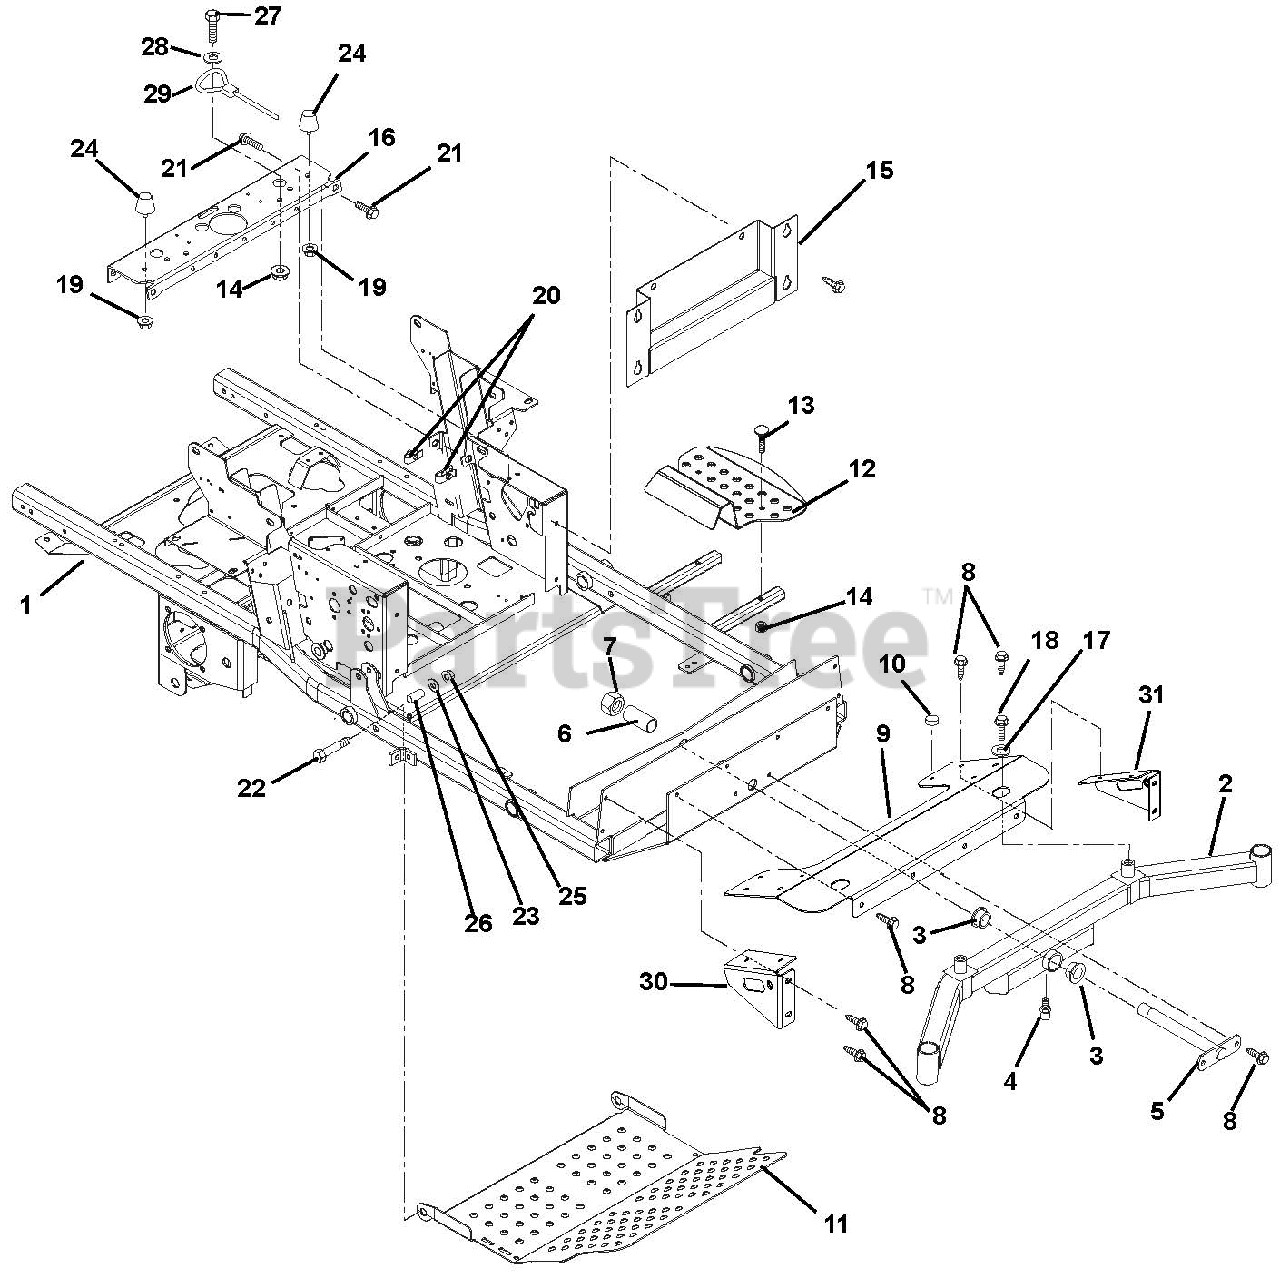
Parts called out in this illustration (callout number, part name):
1	Weldment, Frame
2	Weldment, Axle
3	Bushing, Flange 1.02 x 1.385 x .75 x 1.75
4	Fitting, Lube 45 Degree GM411031
5	Pin, Axle
7	Nut, Locking Nylon 1.00-14
8	Screw, Tapping .38-16 x .75
9	Axle Cover
10	Button, Rubber
11	Panel, Inspection
12	Step, Ingress
13	Bolt, Round Head Square Neck .31-18 x 1.75 Grade 5
14	Nut, Locking Top Flange .31-18
15	Plate, Kick
16	Channel, Cross
17	Washer, Flat Steel .640 x 1.81 x .25
18	Bolt, Hex .50-20 x 1.00 Grade 5
19	Nut, Locking Flange .312-18
20	Nut, Retainer .375-16 x .37
21	Bolt, Serrated Hex Flange Washer Head .38-16 x 1.00
22	Bolt, Hex .50-13 x 3.25 Grade 5
23	Washer, Flat Steel .563 x 1.38 x .109
25	Nut-Locking-Top-Flange .50-13
26	Bushing, Flange .515 x .75 x .275 x 1.12
27	Bolt, Hex .31-18 x .75 Grade 5
28	Washer, Flat Steel .344 x 1.25 x .135
29	Cable, Seat Prop.
30	Weldment, RH Axle Cover Support
31	Weldment, LH Axle Cover Support
